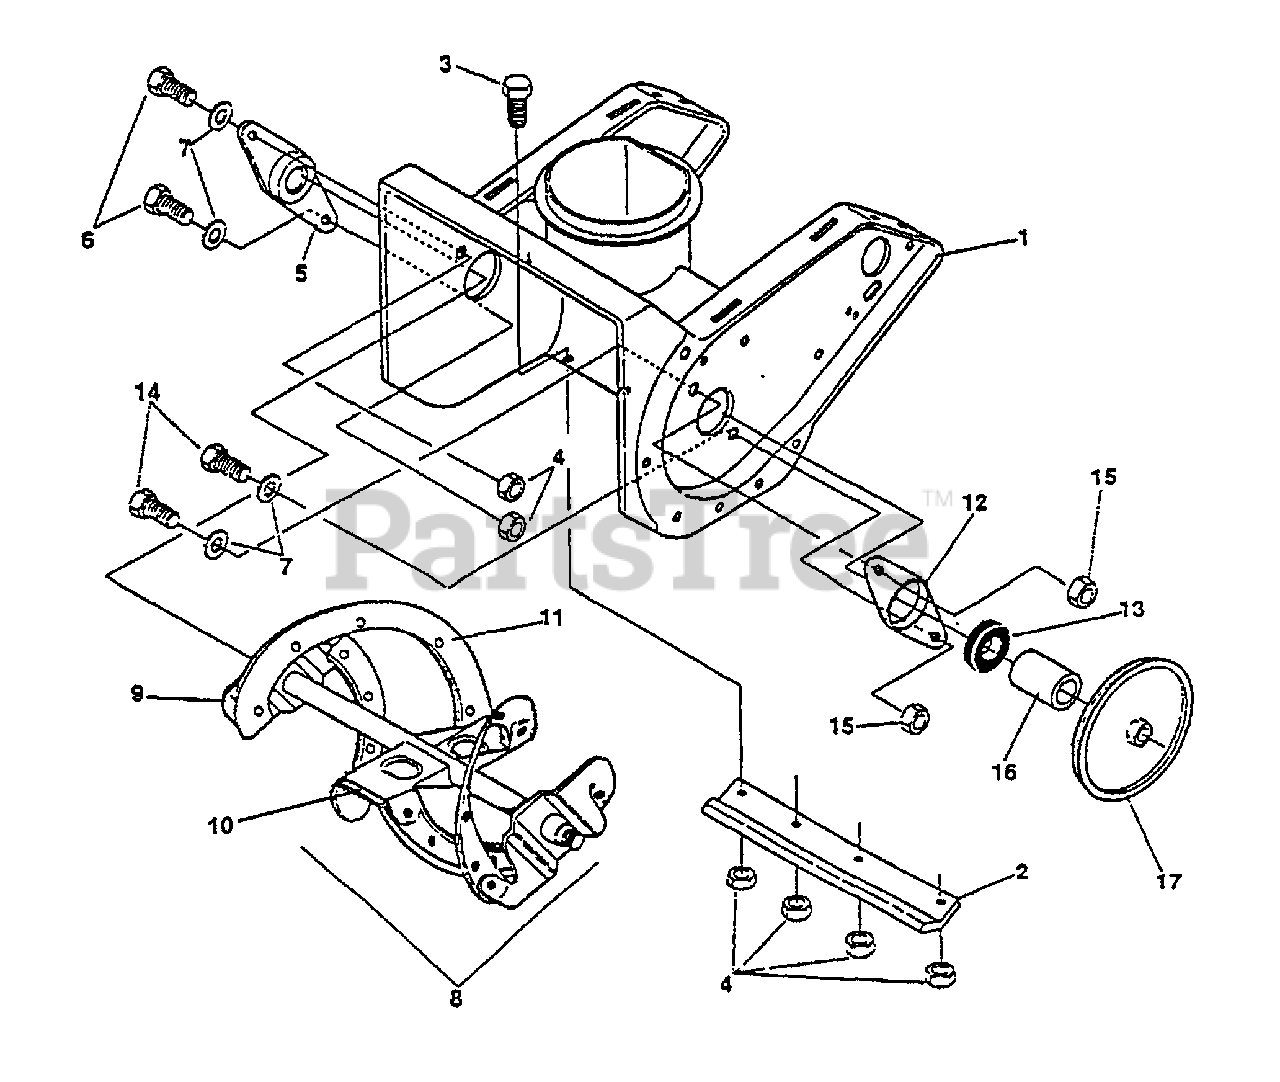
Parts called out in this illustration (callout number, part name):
1	AUGER INTAKE ASSY - 21"
2	BLADE, SCRAPER
3	SCREW - 1/4-20 X 5/8"
4	LOCKNUT - 1/4-20
5	BEARING, FLANGE
6	SCREW - 1/4-20 X .88"
7	WASHER
8	AUGER ASSY
8A	AUGER ASSY - 21"
9	AUGER, BLADE STRIP
10	AUGER, CENTER BLADE STRIP
11	RIVET - .250 X .5"
12	RETAINER, BEARING
13	BEARING, BALL - 6203
14	SCREW - 1/4-20 X .75"
15	NUT - 1/4-20
16	SPACER, SLEEVE .640X.88X.732
17	PULLEY, V3L 6.00X.75 20 GA
